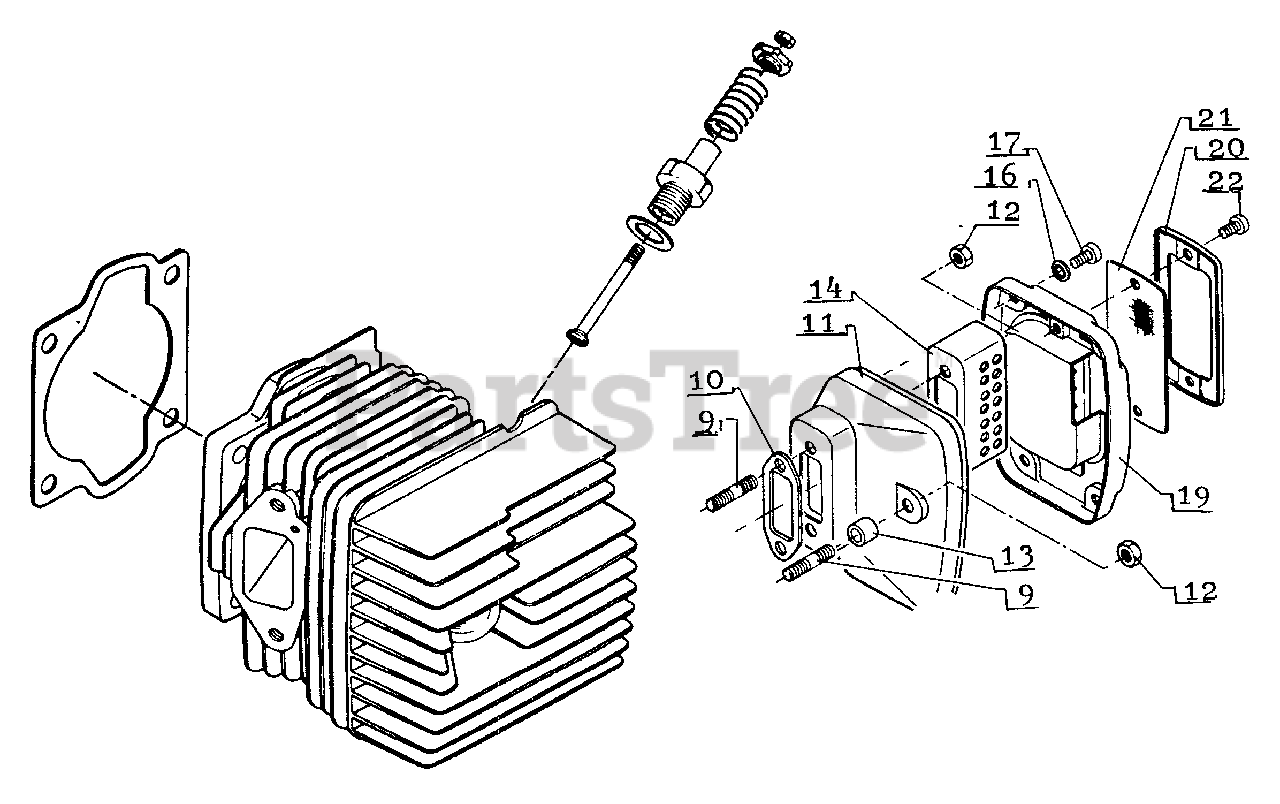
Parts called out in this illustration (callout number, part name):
9	STUD
10	GASKET, EXHAUST
11	MUFFLER
12	LOCKNUT - 6
13	SPACER
14	BAFFLE, MUFFLER
16	LOCKWASHER - 5
17	SCREW - 5X8
19	LID, MUFFLER
20	SCREEN, SPARK ARRESTOR
21	RETAINER, SCREEN
22	SCREW - 5X8
